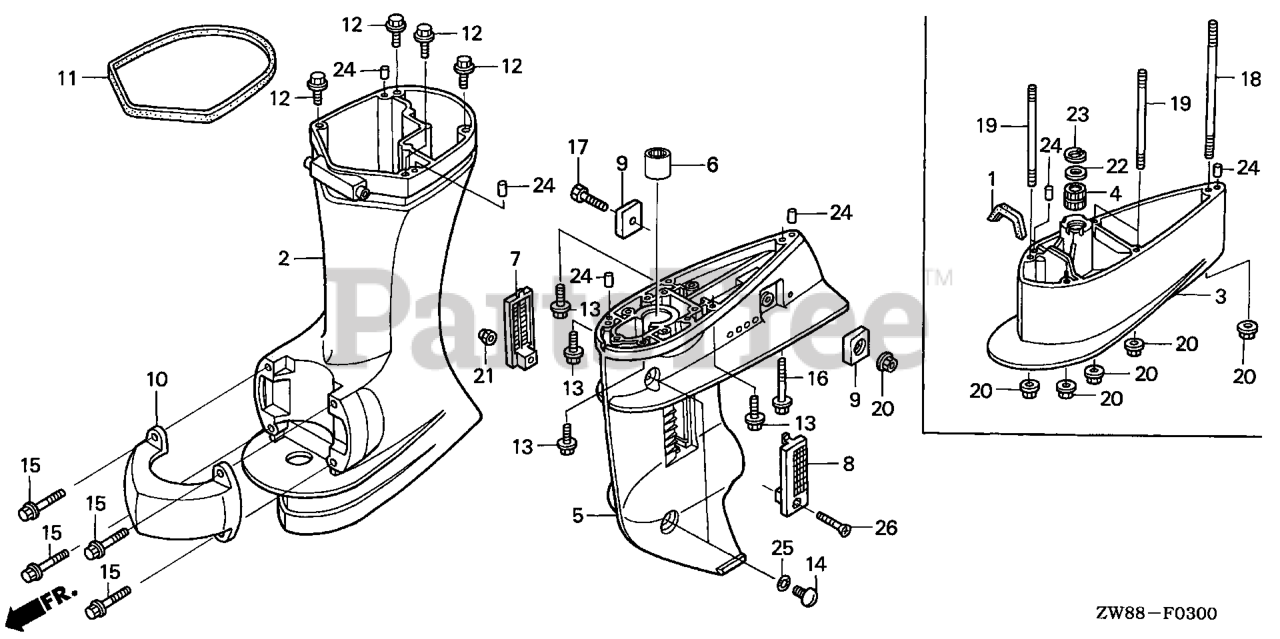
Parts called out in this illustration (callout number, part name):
1	GROMMET, WATER PUMP HOUSING
2	CASE, EXTENSION *NH282MU* (L) (OYSTER SILVER METALLIC-U)
3	SEPARATOR, EXTENSION *NH282MU* (UL) (OYSTER SILVER METALLIC-U)
4	BUSH, VERTICAL SHAFT
5	CASE, GEAR *NH282MU* (UL) (OYSTER SILVER METALLIC-U)
6	BEARING, NEEDLE (15X21X16)
7	SCREEN, R. WATER
8	SCREEN, L. WATER
9	METAL, ANODE
10	HOUSING, MOUNTING (LOWER) *NH282MU* (OYSTER SILVER METALLIC-U)
11	RUBBER, COVER (LOWER)
12	BOLT, FLANGE (8X35) Use from Frame SN 4800713.
14	BOLT, OIL CHECK
15	BOLT, FLANGE (6X20) (ENGINE NO.)
17	BOLT, HEX. (6X25) Use up to Frame SN 4800342.
18	BOLT, STUD (6X211)
19	BOLT, STUD (6X162)
20	NUT, SELF-LOCK (6MM)
21	NUT, SELF-LOCK (5MM)
22	WASHER (20MM)
23	CIRCLIP (INNER) (30MM)
24	PIN, DOWEL (6X10)
25	O-RING (5.5X1.5)
26	SCREW, OVAL (5X28)
